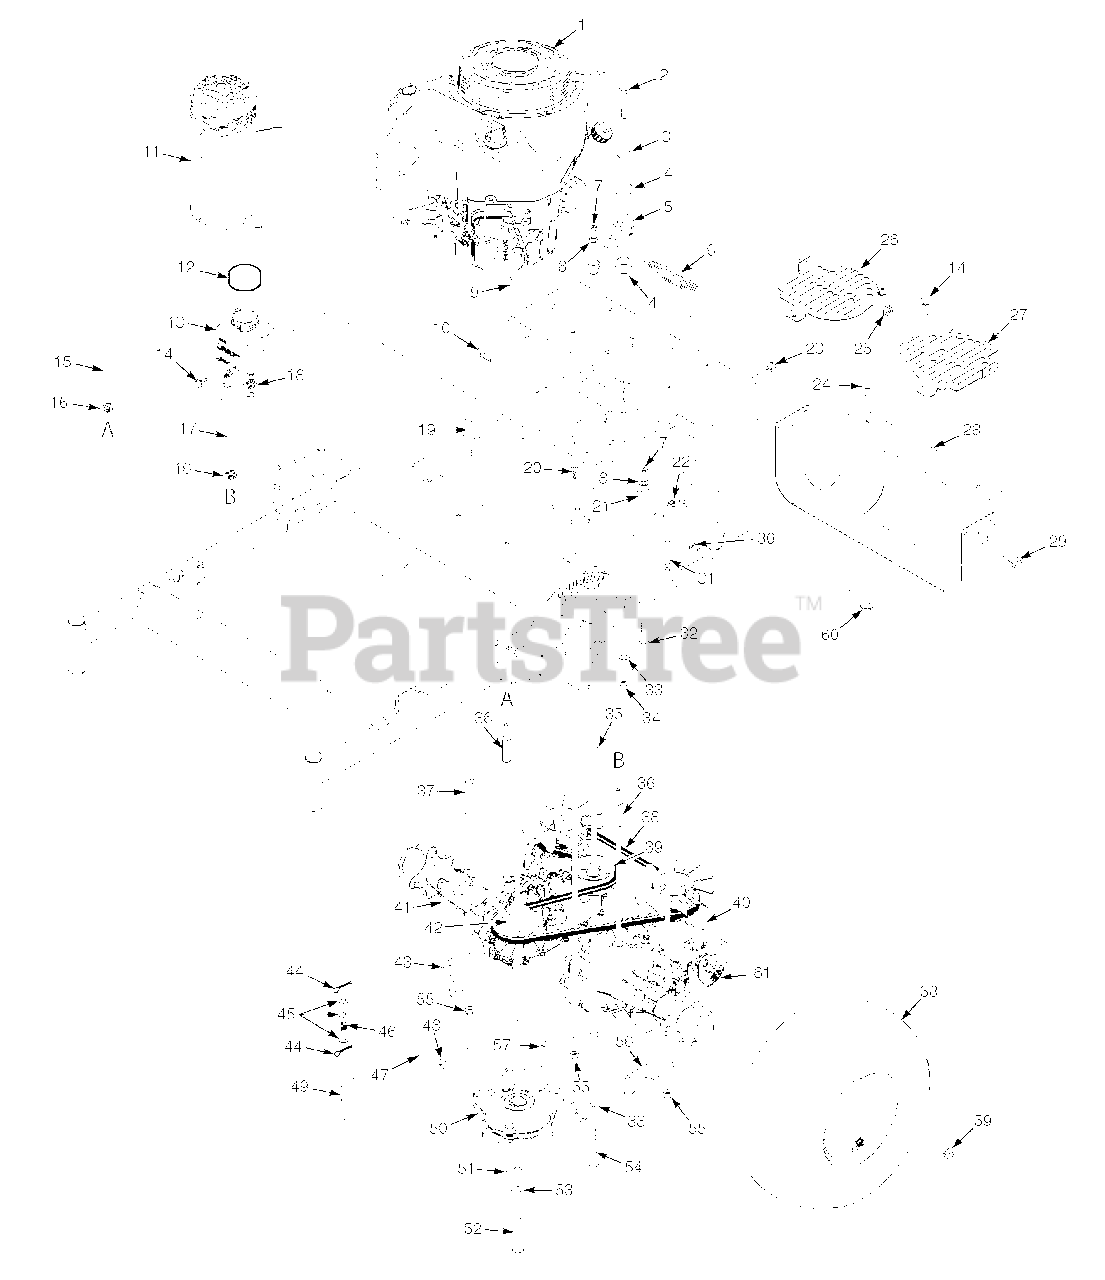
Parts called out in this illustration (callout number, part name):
1	Engine, Kawasaki FS481V
1	Engine, Kawasaki FS541V
1	Engine, Kawasaki FS600V (Recoil Start)
1	Engine, Kawasaki FS600V (Electric Start
2	Bolt, Hex Head 3/8-16 x 3"
3	Pivot, Idler
4	Bearing
5	Idler Arm
6	Spring, Transmission Idler
7	Nut, Center Lock 3/8-16
8	Nut, Serrated Flange 3/8-16
9	Key, 1/4 x 1/4 x 2-1/2"
10	Bolt, Carriage 1/4-20 x 3/4"
11	Muffler, Kawasaki FS/FX
13	Reservoir Assembly
14	Bolt, Hex Head, Serrated Flng 1/4-20 x 3/4"
15	Hose, RH Transmission
16	Clamp, 0.69" Max Dia.
17	Hose, LH Transmission
18	Clamp, 0.87" Max Dia.
19	Bolt, Hex Head 5/16-18 x 6-1/2"
20	Bolt, Carriage 5/16-18 x 1"
21	Spacer
22	U-Nut, 1/4-20
23	Nut, Elastic Stop 1/4-20
24	Bolt, Carriage 5/16-18 x 3/4
25	Nut, Serrated Flange 1/4-20
26	Fan Cover, RH
27	Fan Cover, LH
28	Skid Plate
29	Cpscrw, 5/16-18 x 3/4"Serrated Flange HH
30	Nut, Serrated Flange 5/16-18
31	Bolt, Hex Head 5/16-18 x 3"
32	Bolt, Hex Head 3/8-16 x 1-3/4"
33	Flatwasher, 3/8-.391 x .938 x .105 Hardened
34	Nut, Elastic Stop 3/8-16
35	Spacer
36	Fitting, Transmission
37	Spacer, Axle
38	Belt, Transmission Drive
39	Pulley, 3-1/2" Dia.
40	Transaxle Assy., (ZH-GMCC-3LUB-1MXX)
41	Transaxle Assy., (ZH-KMCC-3LUC-1MXX)
42	Pulley, 4-1/2" Dia. 1" Bore
43	Pusharm Mount Bracket, RH
44	Cotter Pin, 3/32 x 1"
45	Flatwasher, 1/4-.312 x .750 x .065
46	Spring, Dump Valve Link
47	Pin, Rue Cotter 3/8" Dia.
48	Joint, Swivel
49	Link, Dump Valve
50	Electric Clutch Assembly
51	Flatwasher, 7/16-.469 x 1.75 x .25
52	Bolt, Hex Head 7/16-20 x 3" w/t Patch
53	Lockwasher, 7/16" spring
54	Bolt, Hex Head 3/8-16 x 3-3/4"
55	Nut, Elastic Stop 5/16-18
56	Pusharm Mount Bracket, LH
57	Bracket, Anti-Rotation
58	Wheel Assembly 18 x 6.5-8 (36" Only)
58	Tire 18 x 6.5-8 (36" Only)
58	Wheel Assembly 18 x 8.5-8 (48" Only)
58	Tire 18 x 8.5-8 (48" Only)
59	Wheel Nut, 1/2-20
60	Nut, Push-On 5/16-18
61	Spring, RTN
